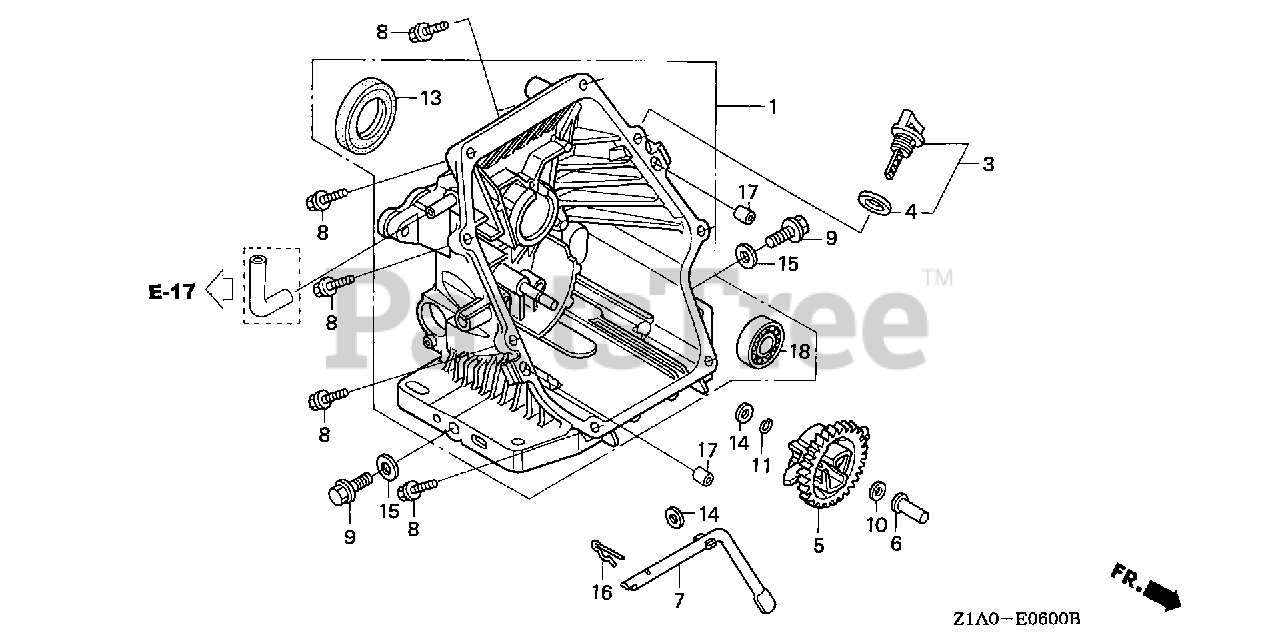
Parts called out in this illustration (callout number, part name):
1	COVER ASSY., CRANKCASE
3	CAP ASSY., OIL FILLER
4	GASKET, OIL FILLER CAP
5	GOVERNOR ASSY.
6	SLIDER, GOVERNOR
7	SHAFT, GOVERNOR ARM
8	BOLT, FLANGE (6X25) Use up to Engine SN 2056819.
9	BOLT, DRAIN PLUG
10	WASHER, THRUST (6MM)
11	CLIP, GOVERNOR HOLDER
13	OIL SEAL (28X41.25X6)
14	WASHER, PLAIN (6MM)
15	WASHER, DRAIN PLUG (12MM)
16	PIN, LOCK (8MM)
17	PIN, DOWEL (8X20)
